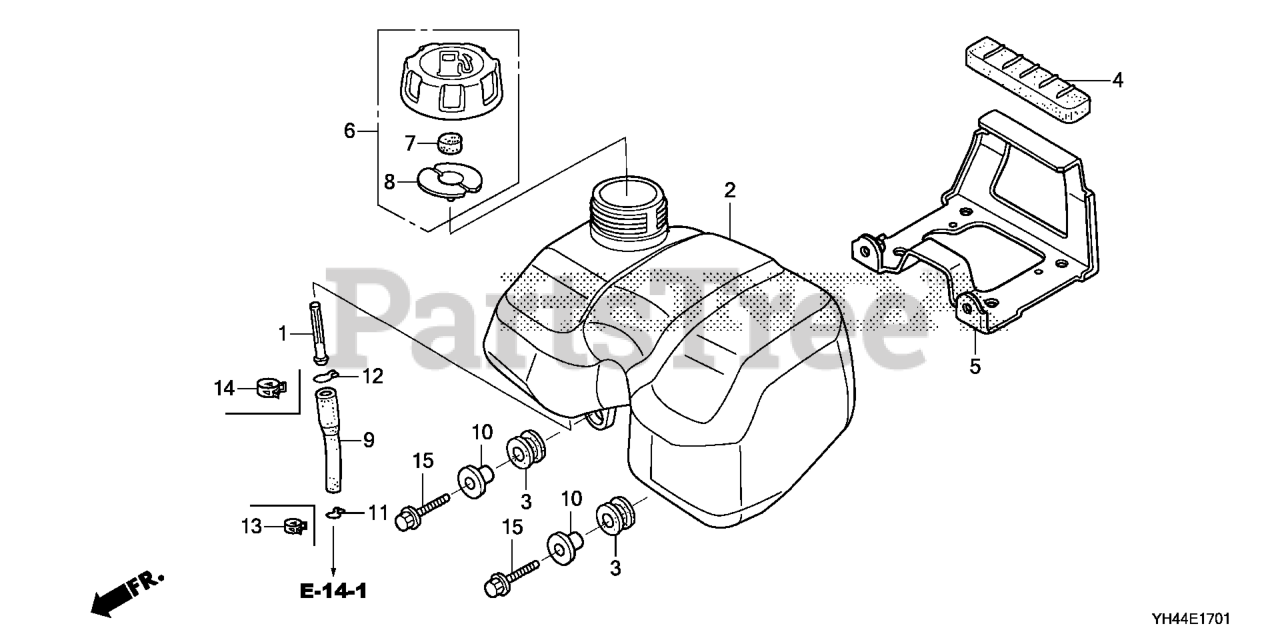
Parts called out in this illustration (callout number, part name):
1	FILTER, FUEL
2	TANK, FUEL
3	RUBBER A, TANK MOUNTING
4	RUBBER B, TANK MOUNTING
5	STAY, FUEL TANK
6	CAP ASSY., FUEL TANK
7	SPONGE, FUEL CAP BREATHER
8	GASKET, FUEL CAP
9	TUBE A, FUEL (FKM)
9	TUBE A, FUEL
10	COLLAR, CANISTER MOUNTING
13	CLIP, TUBE (D8)
14	CLIP, TUBE (10.5MM)
15	BOLT, FLANGE (6X20)
